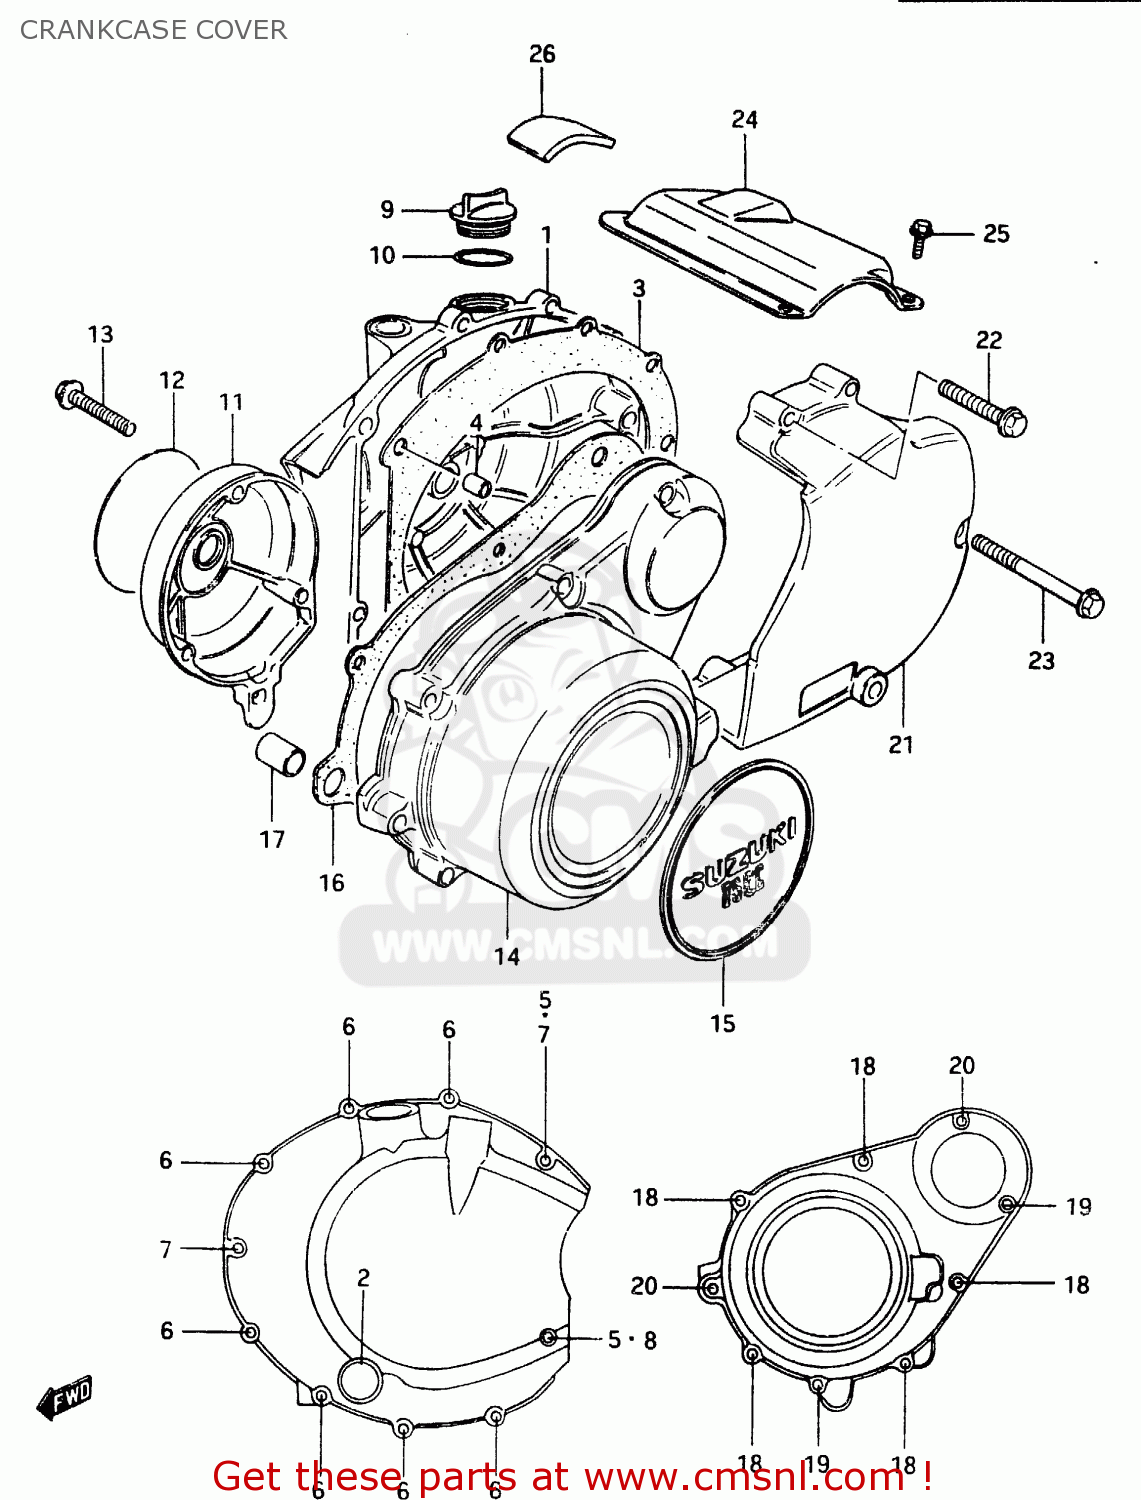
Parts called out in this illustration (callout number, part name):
1	COVER, CLUTCH
2	LENS,OIL LEVEL CHECK
3	GASKET (MCA)
4	PIN
5	GASKET (NAS)
6	BOLT (6X25)
7	BOLT (6*30)
8	BOLT (6X45)
9	PLUG
10	O-RING
11	COVER,CONTACT
12	EMBLEM,CONTACT BREAKER COVER
13	BOLT (5X30)
14	COVER, GENERATOR
15	EMBLEM,MAGNETO COVER
16	GASKET (MCA)
17	PIN
18	BOLT (6*30)
19	BOLT (6X35)
20	BOLT (6X40)
21	COVER, ENGINE SPROCKET
22	BOLT (6X35)
23	BOLT (6X65)
24	COVER,STARTER MOTOR
25	BOLT (5X8)
26	DAMPER,STARTER MOTOR CLUTCH
